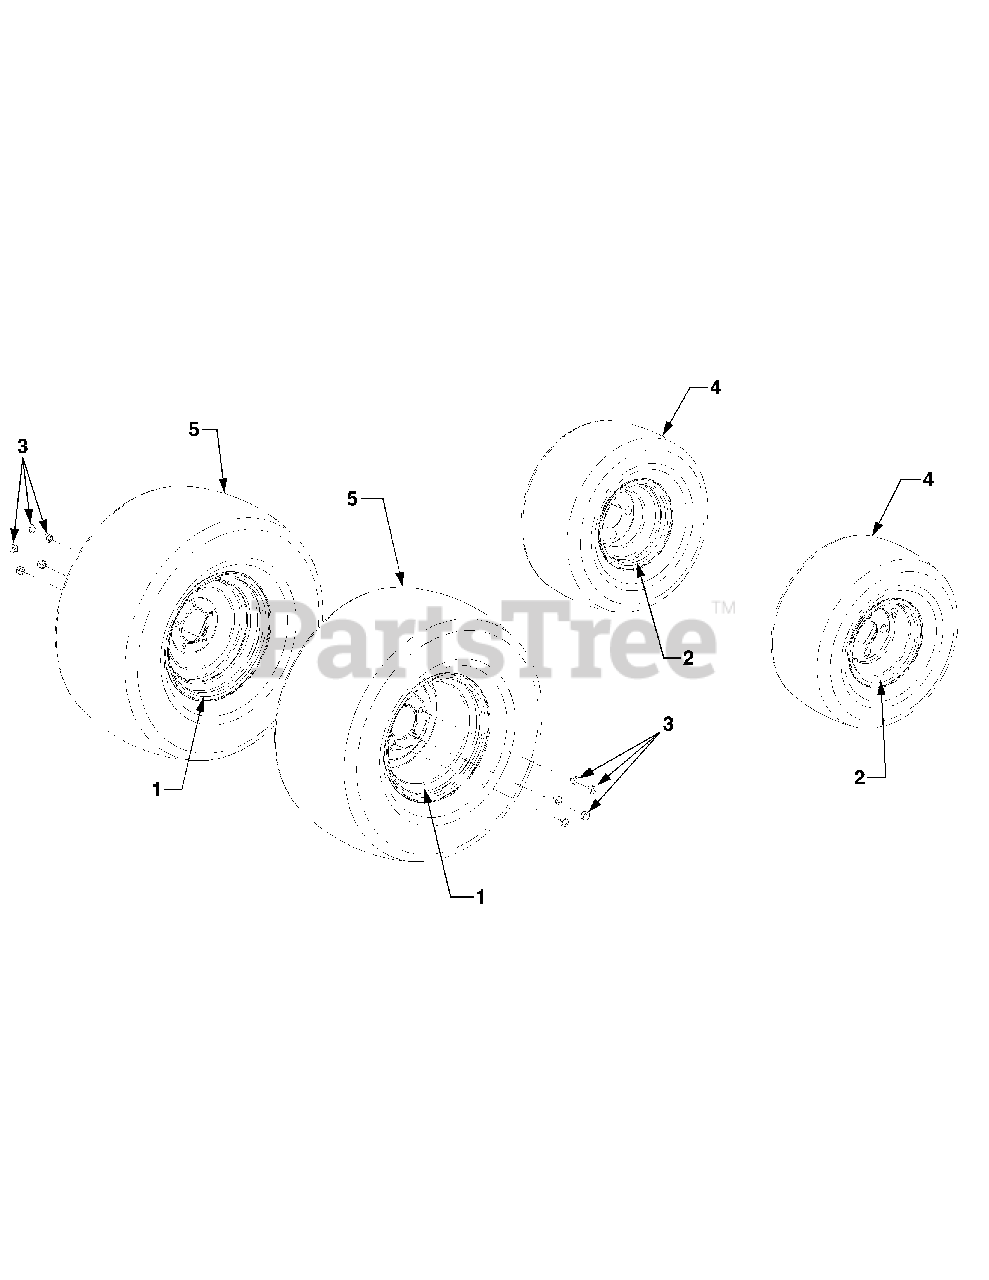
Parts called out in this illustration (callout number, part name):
1	Rim Assembly
1	Valve Stem
2	Rim Assembly
2	Valve Stem
3	Nut, Lug, 7/16-14
4	Tire, Tuft, 18 x 8.5 x 8
5	Tire, Turf, 26 x 12.0 x 12
